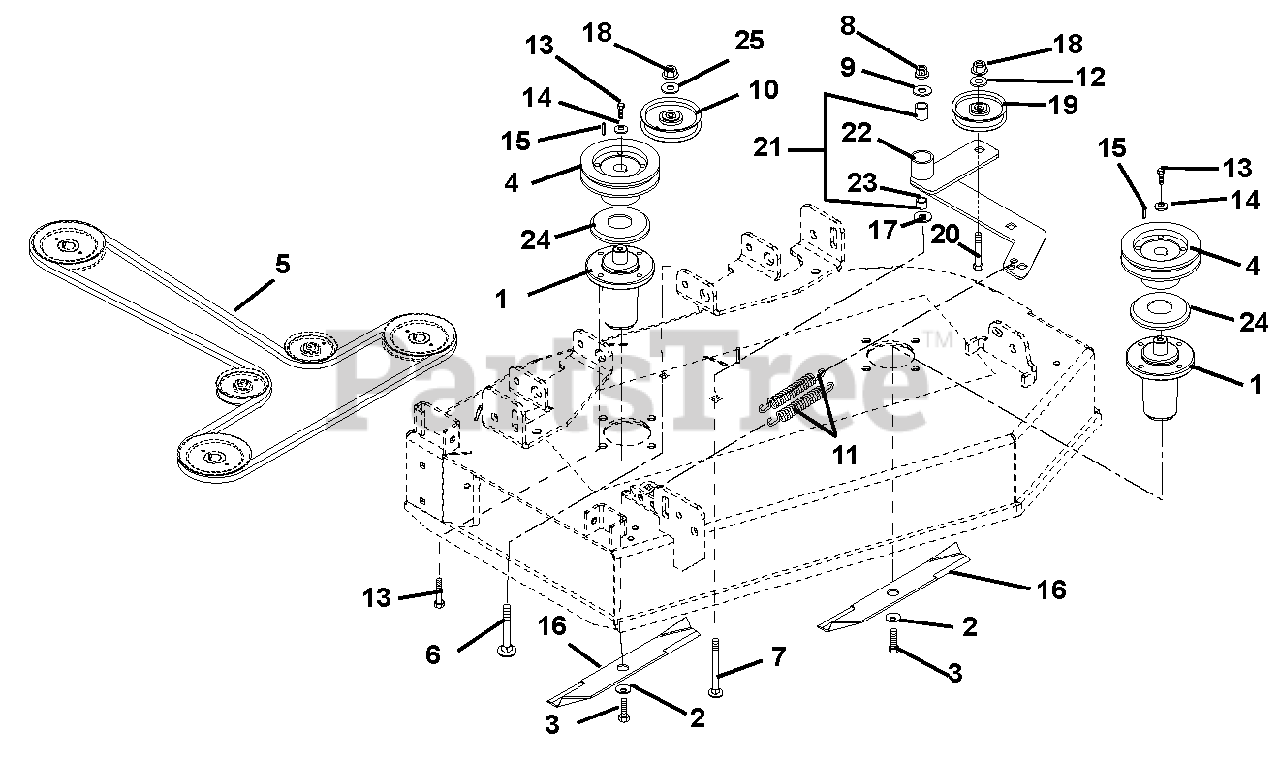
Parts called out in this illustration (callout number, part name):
1	Assembly, Maintenance Free Spindle
2	Washer-Bellville .63 x 1.625 x .14
3	Bolt-Hex .62-18 x 1.75 Grade 8
4	Sheave, 5.00 Spindle (1.00 I.D.)
5	V-Belt, B-Section 49.68 x .62548.80 x .625
6	Bolt-Round Head Square Neck .38-16 x 3.00 Grade 5
7	Bolt, Round Head Square Neck .50-13 x 3.50 Grade 5
8	Nut, Nyloc Flange .50-13
9	Bearing, Pedestal
10	Idler-Flat 4.00 x .38 (2.00 W)
11	Spring, Extension
12	Washer, Flat-Steel .375 x 1.125 x .065
13	Bolt, Hex .38-16 x 1.00 EP30
14	Washer, Flat-Steel .406 x 1.50 x .245
15	Key, Square .25 x .25 x 1.00 RC 40-50
16	Blade, Mower Hi-Lift
16	Blade, Mulching 50" Mower
17	Washer, Flat Steel .531 x 1.250 x .100
18	Nut, Nyloc Flange 3/8-16
19	Idler, Flat 4.00 x .38 (1.00 W)
20	Bolt, Round Head Square Neck .38-16 x 2.00 Grade 5
21	Assembly, Idler Pivot Arm (Contains Items 22 & 23)
22	Weldment, Idler Pivot Arm
23	Bushing, 1.00 x 1.125 x 1.936
24	Slinger-Dust
25	Seal, Idler Bearing
